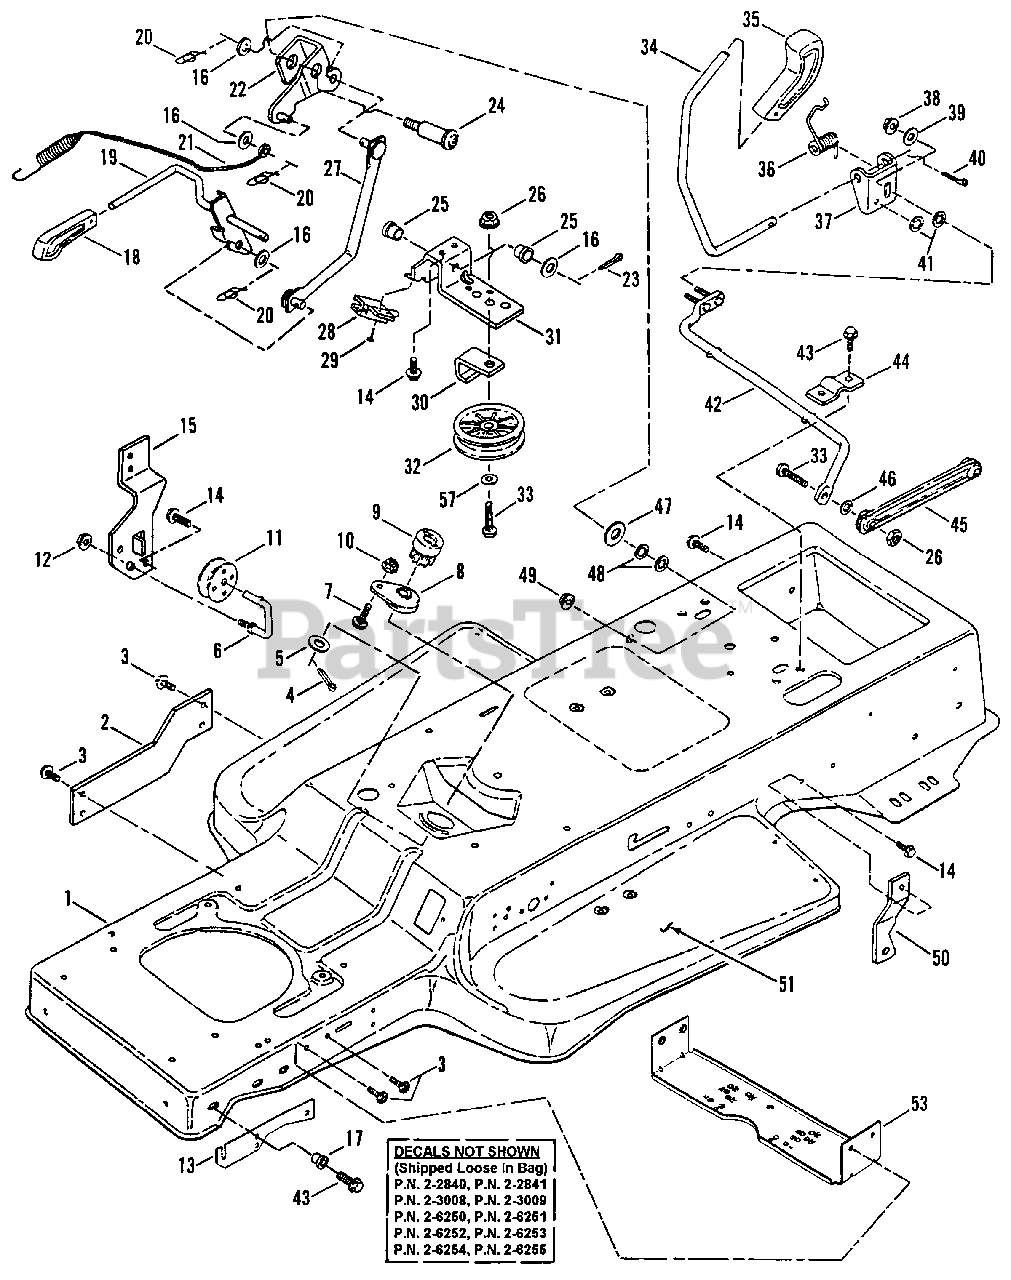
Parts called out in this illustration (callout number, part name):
1	FRAME, Tractor
2	BRACE, Frame
3	SCREW, 5/16-18 x 5/8" Truss Head (Torx)
4	PIN, 1/8 x 3/4" Cotter
5	WASHER, 1/2 Shim
6	ROD, Spool Pivot
7	NUT, 1/4-20 Hex Flange Lock
8	ASSEMBLY, Steering Adjuster
9	GEAR, Steering Pinion
10	BOLT, 1/4-20 x 5/8" Short Neck Carriage
11	SPOOL
12	NUT, 5/16-18 Hex Flange Lock
13	BRACKET, Hood Pivot
14	SCREW, 5/16-18 x 5/8" Self-Tap.
15	BRACKET, Axle/Spool
16	WASHER, 3/8" Flat
17	BUSHING, Flange
18	KNOB, Deck Engagement
19	WELDMENT, PTO Lever
20	PIN, 3/64 x 1 7/32" (Self-Locking)
21	CABLE, Blade 13.95"
22	WELDMENT, PTO Bellcrank
23	PIN, 3/32 x 3/4" Cotter
24	BOLT, 1/2-13 x 2 11/32" Shoulder
25	BUSHING
26	NUT, 3/8-16 Hex Center Lock
27	ROD, PTO Link
28	SWITCH
29	SCREW, #10-24 x 1/2" Hex Washer Self-Tap (Torx)
30	GUIDE, Belt
31	SUPPORT, PTO Lever
32	PULLEY
33	SCREW, 3/8-16 x 1 1/2" Hex Hd. Cap
34	LEVER, Shift
35	KNOB, Deck Lift Lever
36	SPRING, Shift Lever
37	BRACKET, Shift Lever (Upper)
38	NUT, 1/4-20 Hex Flange Lock
39	WASHER, 1/4 Flat
40	PIN, 5/32 x 1" Cotter
41	WASHER, 1/4 Internal Tooth Lock
42	ASSEMBLY, Shift Lever (Lower)
43	SCREW, 5/16-18 x 1 1/4" Self-Tap.
45	LINK, Shift Lever
46	SPACER
47	WASHER, Thrust
48	WASHER, 1/2 Internal Tooth Lock
49	NUT, 1/2-13 Hex Flange Lock
50	BRACKET, Torque
51	PAD, Foot, Rubber Deluxe
53	BRACKET, Belt Guide
57	WASHER, 3/8" Flat
